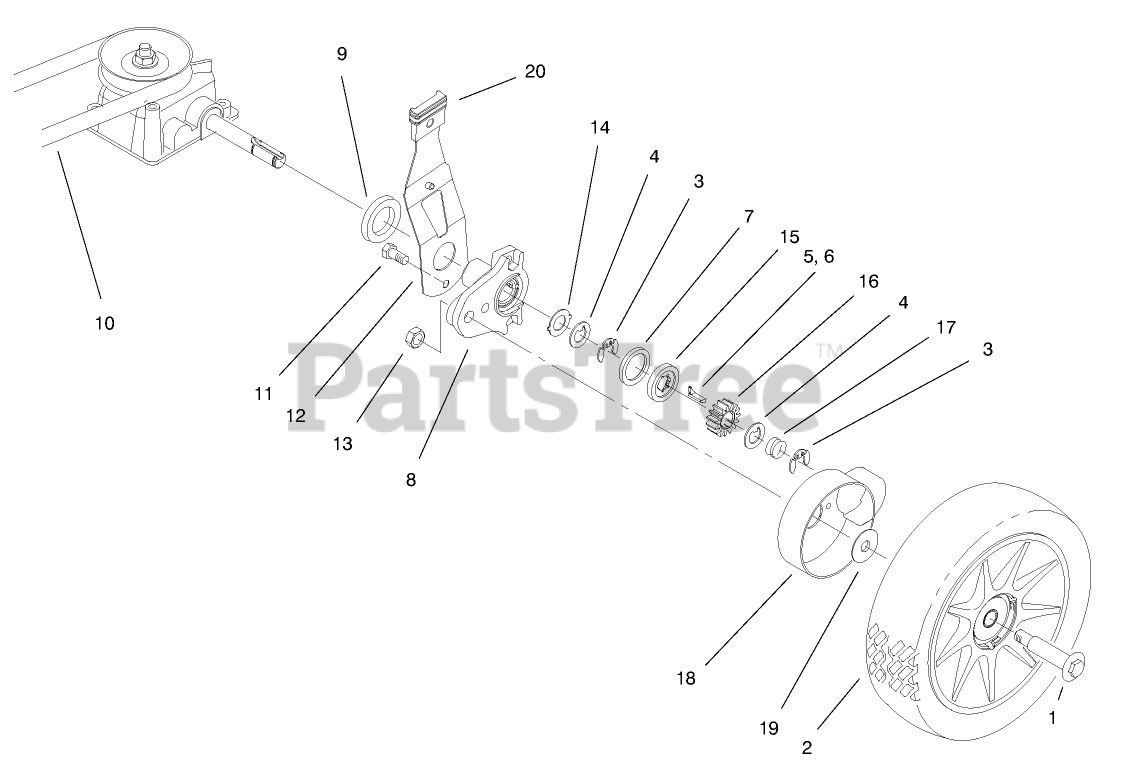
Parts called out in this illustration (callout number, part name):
1	BOLT-SHOULDER
2	WHEEL AND TIRE ASM
3	RING-RETAINING,CLIP
4	WASHER-THRUST, KEYED
5	KEY-ROCKING, LH
6	KEY-ROCKING, RH
7	RING-FRICTION
8	REAR HEIGHT ADJUSTMENT ARM ASM
9	SPACER-SHAFT, AXLE
10	V-BELT
11	SCREW-HWH
12	REAR SPRING ARM ASM
13	NUT-JAM, LOCKING
14	WASHER-ARM, PIVOT
15	WASHER-CLUTCH
16	GEAR-PINION
17	SPRING-COMPRESSION
18	COVER-WHEEL
19	WASHER-STEPPED
20	KNOB-LEVER, HEIGHT ADJUSTMENT
